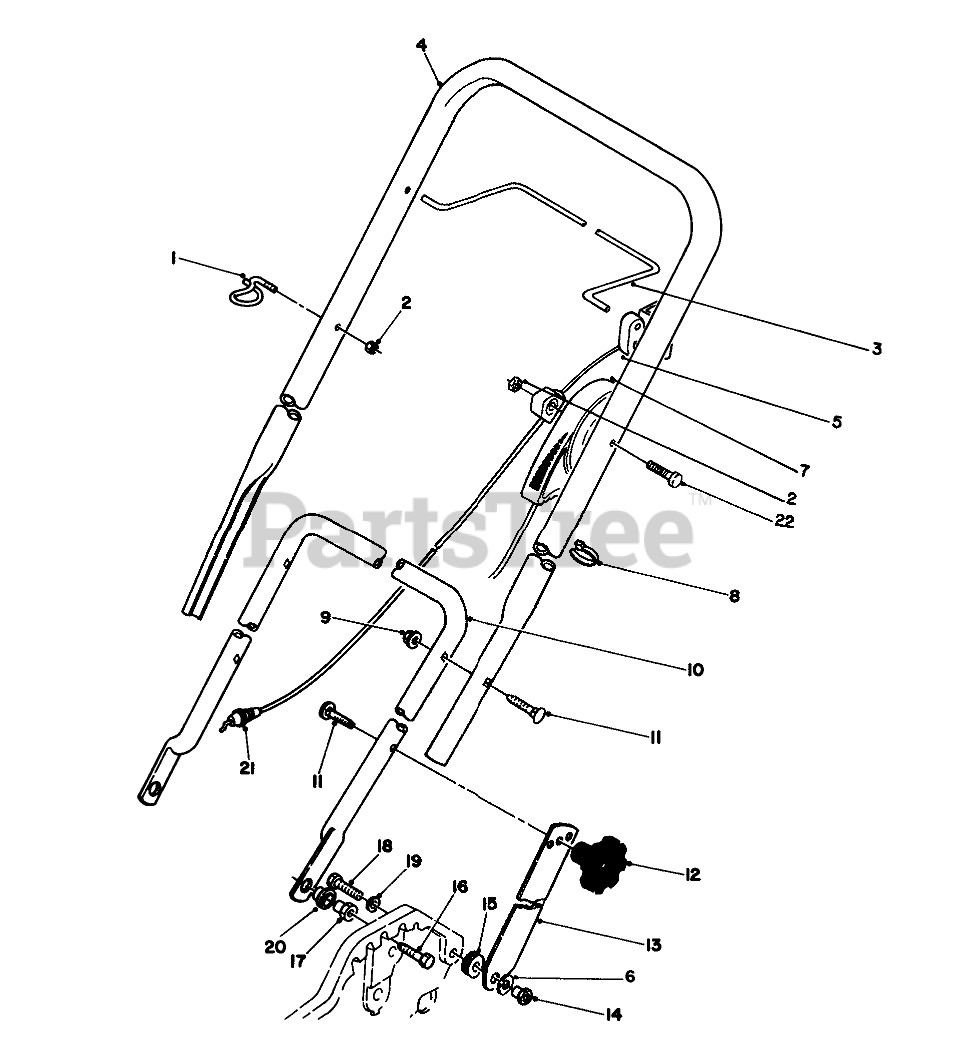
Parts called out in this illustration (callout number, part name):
1	GUIDE-ROPE
2	NUT-LOCK, NI
3	Bar-Control
4	UPPER HANDLE
5	STOP-PIVOT
6	WASHER
7	THROTTLE CABLE
8	TIE-CABLE
9	NUT-LOCK NI
10	LOWER HANDLE(CROM)
11	SCREW-HANDLE
13	HANDLE LATCH
14	POST-MOUNTING, LINKAGE
15	GROMMET
16	SCREW-HH
17	HANDLE PIVOT NUT
18	SCREW-HH
19	WASHER-LOCK
20	FLANGE BUSHING
21	BRAKE CABLE
22	SCREW-HH
